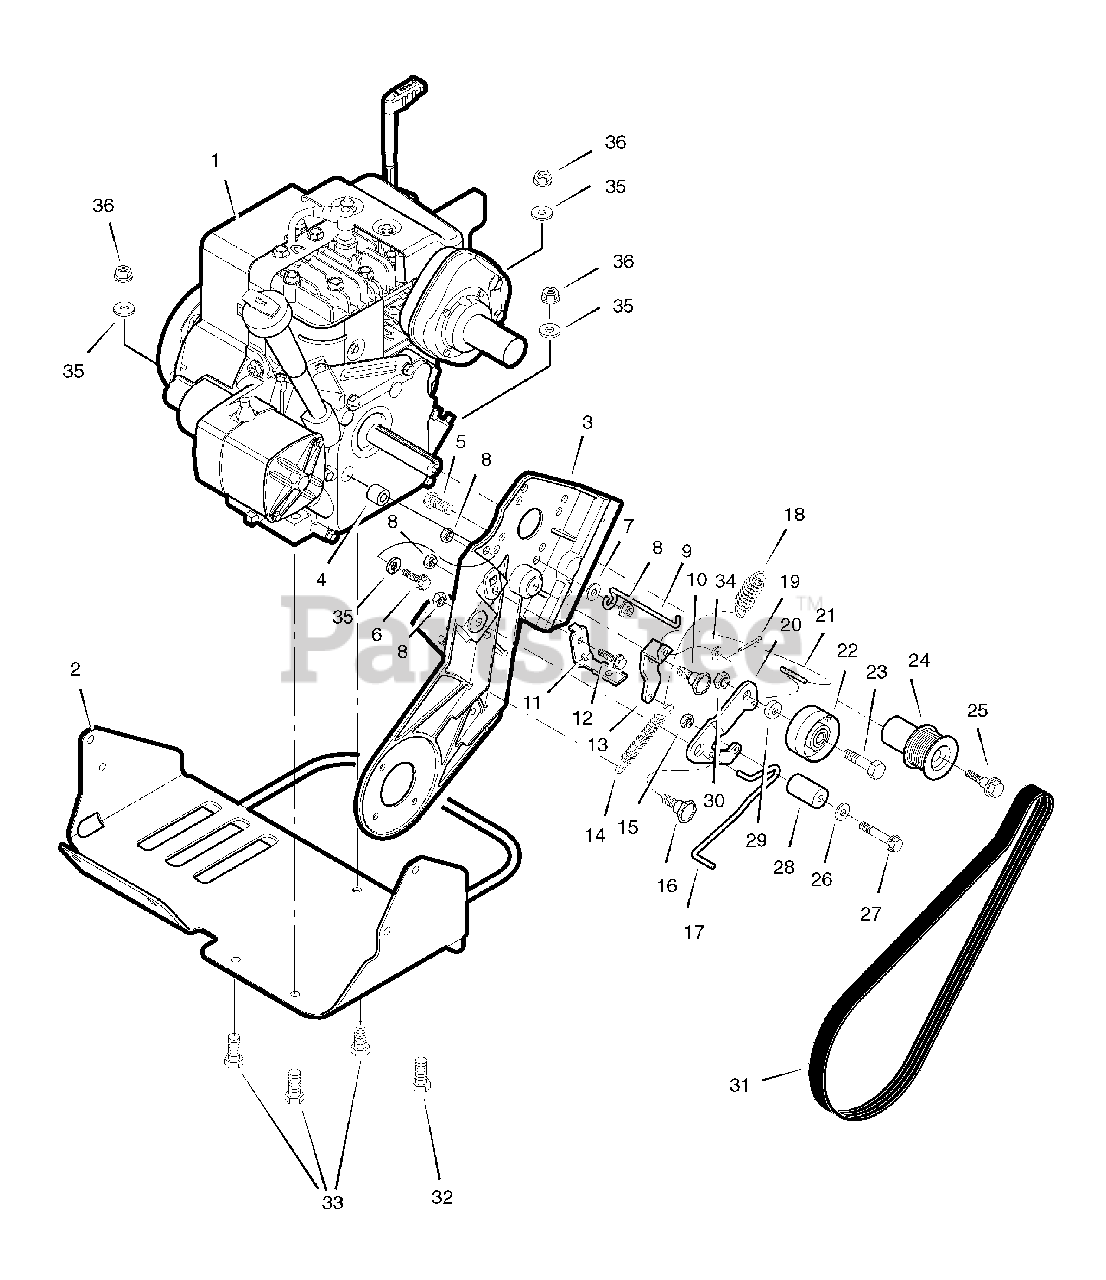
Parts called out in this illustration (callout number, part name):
1	* ENGINE, 5.25GT 4CY Briggs & Stratton Electric Start
2	CRADLE ASSEMBLY, Engine
4	ANTI-VIBRATION MOUNT, Engine
5	BOLT, Hex, 5/16-18
6	BOLT, Hex, 5/16-24
7	WASHER, Flat
8	NUT, Hex Center Lock, 5/16-18
9	GUIDE, Belt
10	BOLT, 1/2 x 11/64
11	PAD, Brake
12	SCREW, 1/4-20 x 5/8
13	IDLER, Arm Pivot
15	NUT, Hex 1/4-20
16	BOLT, 1/2 x 11/64
17	WIRE, Brake
19	PIN, Cotter
21	ROD, Clutch Linkage
22	PULLEY, Idler
23	SCREW, 3/8-16 x 1-5/8
24	PULLEY, Engine
25	BOLT, Engine Pulley
26	WASHER, Flat
27	SCREW, 1/4-20 x 2
28	PINCH ROLLER
29	SPACER, Idler
30	NUT, Hex
31	BELT, Drive
32	BOLT, Hex, 5/16-18
33	SCREW, 3/8-16 x 1
34	WASHER, Flat
35	LOCKWASHER, Split
36	NUT, 5/16-18
